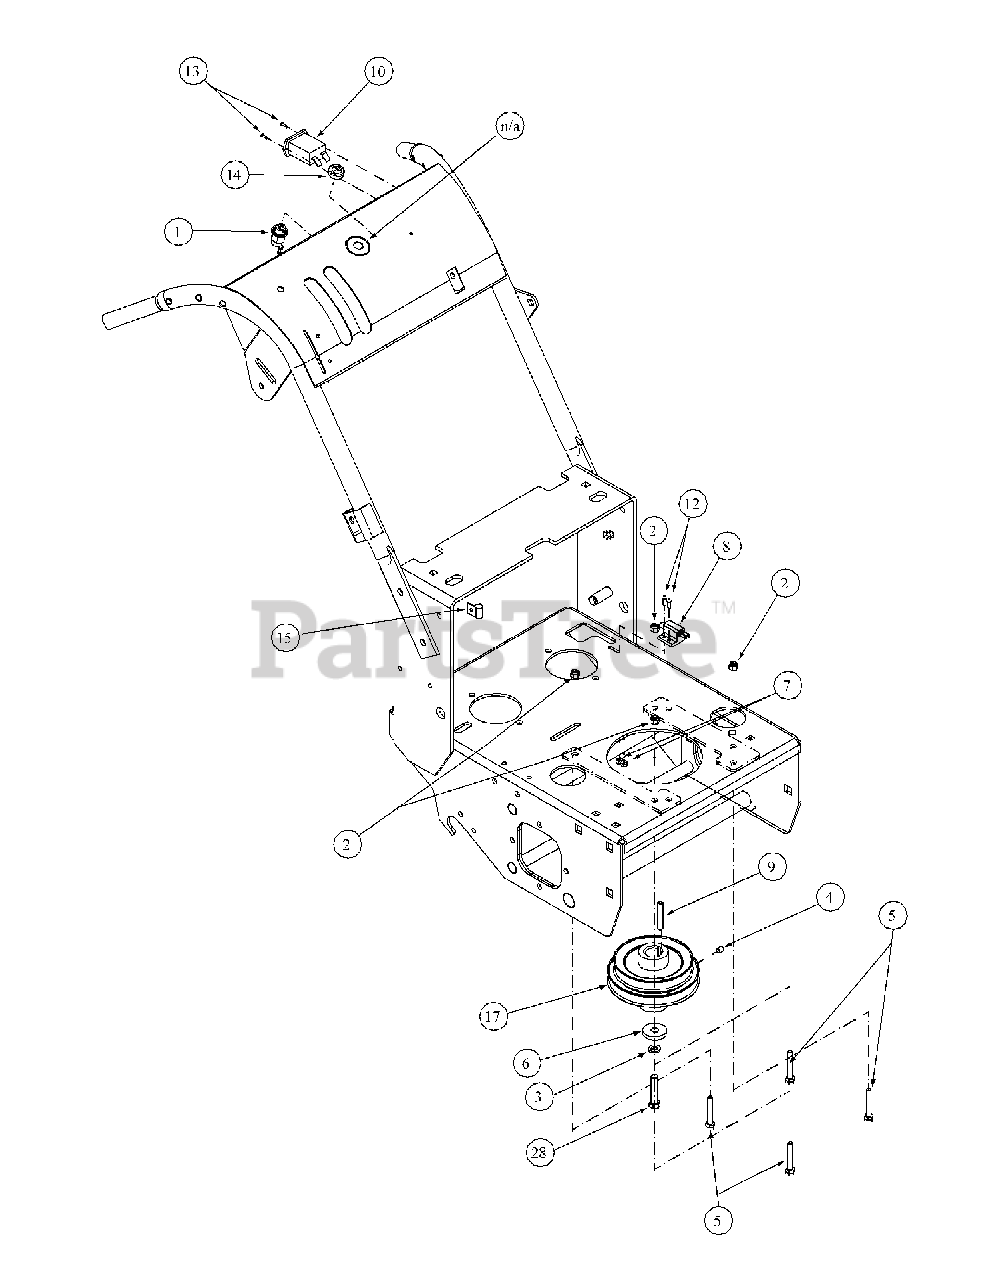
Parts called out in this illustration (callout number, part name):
1	Ignition Switch ON/OFF
2	Nut, Nylock 5/16-18
3	Lock Washer, 7/16
4	Nylock Screw, 5/16-18 x 3/8
5	HHCS, 5/16-18 x 3/8
6	Clutch Washer
7	Nut, Lock Nylon, 10-32
8	Delta Switch
9	Key Stick, 1/4 x 1/4 x 2
12	Screw 10-32 x 5/8
13	Rivet
14	Nut w/Cap, 5/8-32 Ignition
15	Support Clamp 3/8
17	Double Pulley
28	Capscrew, 7/16-20 x 2"
